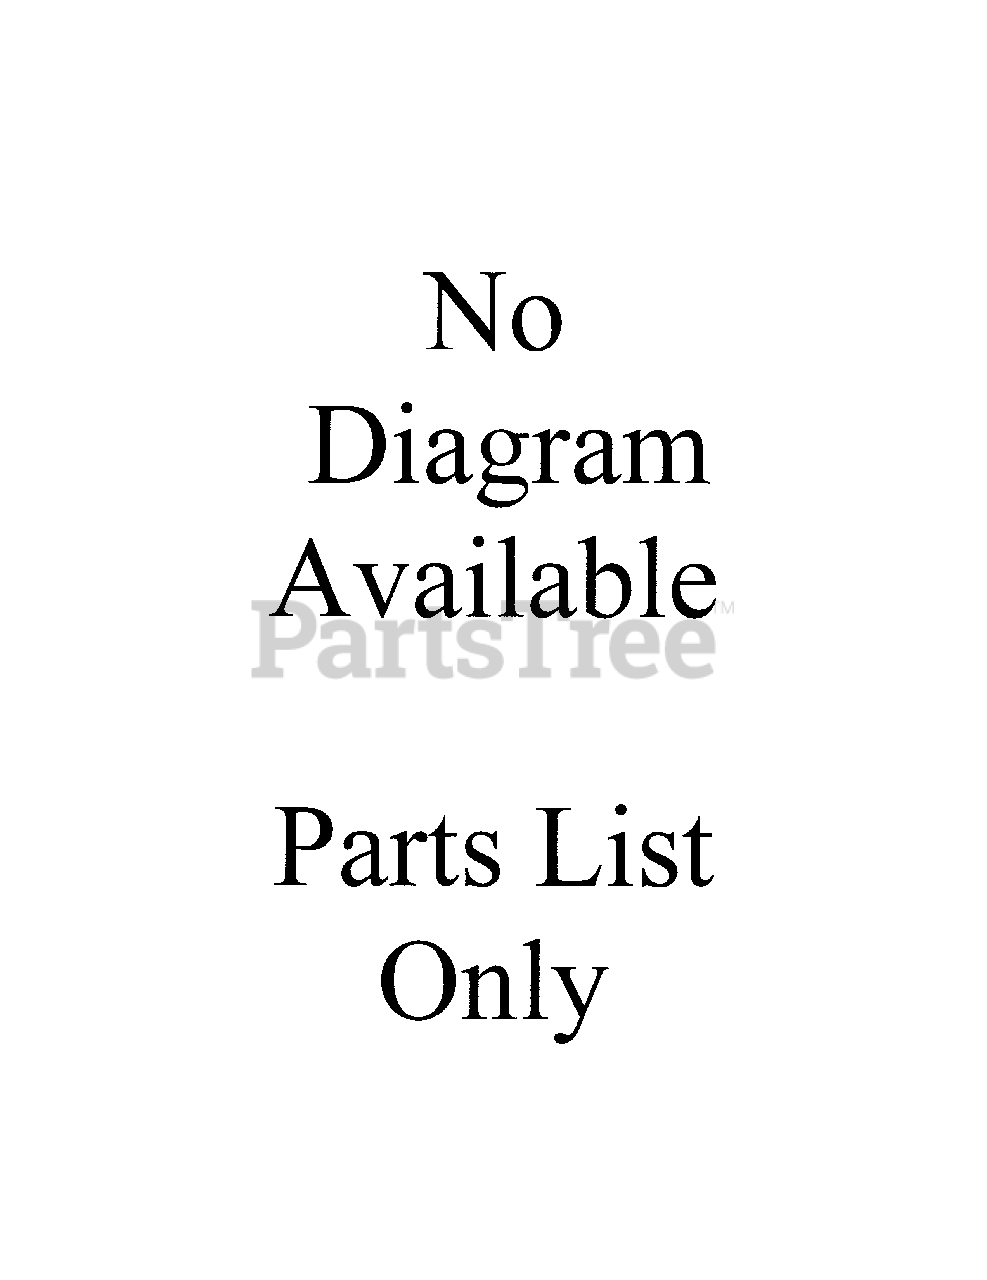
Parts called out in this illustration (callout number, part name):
1	"Cylinder (Incl. 2,20 & 125)
2	Dowel Pin
6	Breather Element
7	Breather Body Ass'y. (Incl. 6 & 12A)
12A	Breather Cover & Tube (Incl. 12B)
12B	Breather Tube Elbow
14	Flat Washer
15	Governor Rod (Incl. 14)
16	Governor Lever
17	Governor Lever Clamp
18	Screw, Torx T-15, 8-32 x 19/64"
20	Oil Seal
30	Crankshaft
40	Piston, Pin & Ring Set (Std.) (Incl. 41, 42 & 43)
40	Piston, Pin & Ring Set (.010" OS) (In cl. 41, 42 & 43)
40	Piston, Pin & Ring Set (.020" OS) (In cl. 41, 42 & 43)
41	Piston & Pin Assembly (Std.) (Incl. 4 3)
41	Piston & Pin Assembly (.010" OS) (Inc l. 43)
41	Piston & Pin Assembly (.020" OS) (Inc l. 43)
42	Ring Set (Std.)
42	Ring Set (.010" OS)
42	Ring Set (.020" OS)
43	Piston Pin Retaining Ring
45	Connecting Rod Ass'y. (Incl. 46)
46	Connecting Rod Bolt
48	Valve Lifter
50	Camshaft (MCR)
52	Oil Pump Ass'y.
69	Mounting Flange Gasket
70	Mounting Flange Incl. 72 thru 83,306
72	Oil Drain Plug
72A	Oil Drain Plug
75	Oil Seal
80	Governor Shaft
82	Governor Gear Ass'y. (Incl. 81)
83	Governor Spool
86	Screw, 1/4-20 x 1-1/4"
125	Exhaust Valve (Std.) (Incl. 151)
125	Exhaust Valve (1/32" OS) (Incl. 151)
126	Intake Valve (Std.) (Incl. 151)
150	Valve Spring
151	Valve Spring Cap
151A	Intake Valve Seal
169	Valve Cover Gasket
224	Intake Pipe Gasket
224A	* Intake Pipe To Cylinder Gasket
274	Exhaust Gasket
306	"O"-Ring
370	Name Decal
370A	Lubrication Decal
